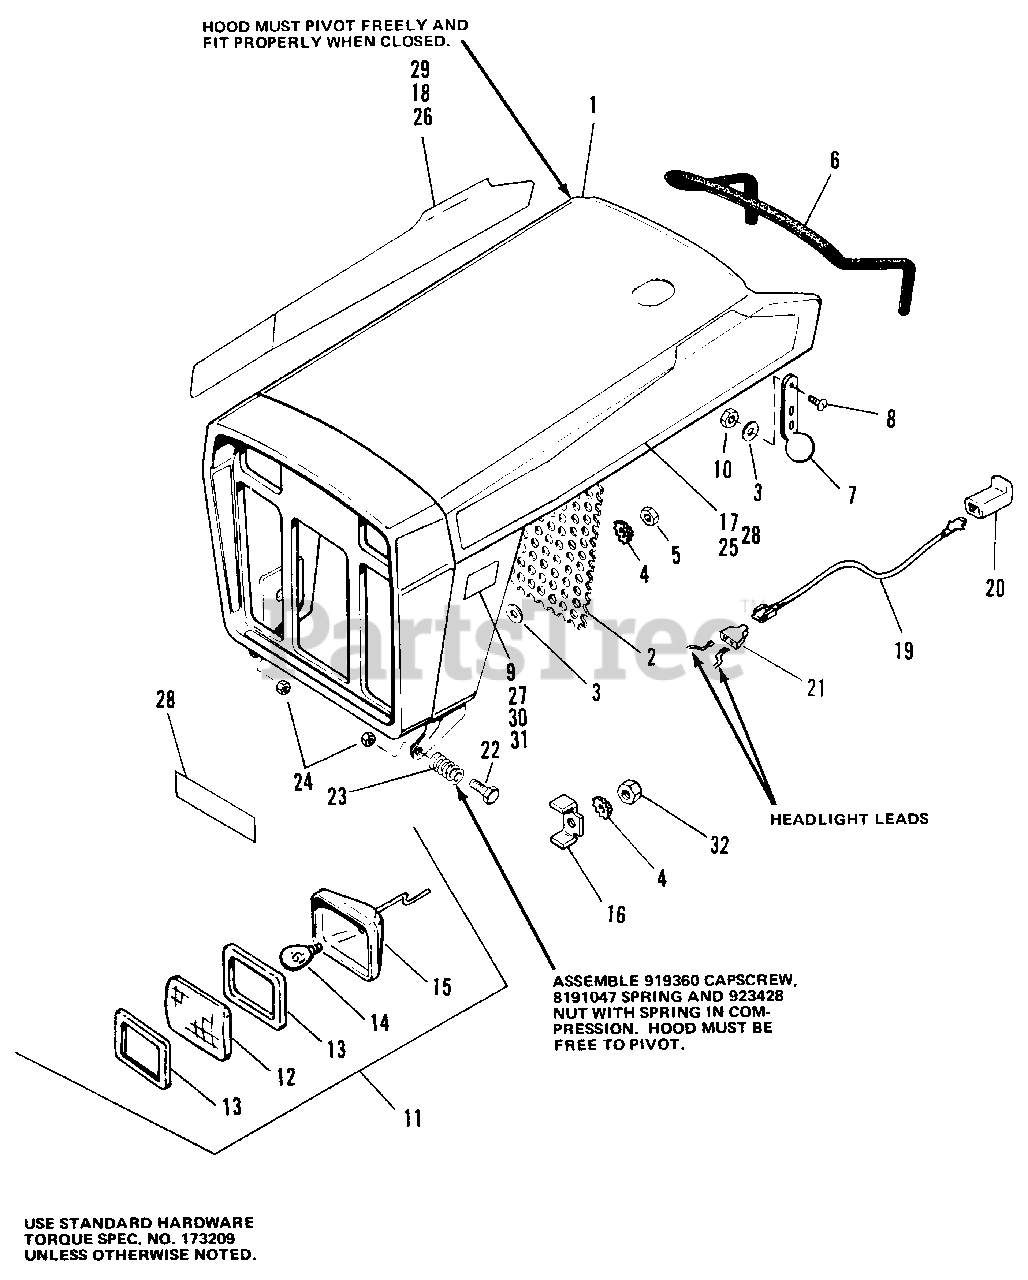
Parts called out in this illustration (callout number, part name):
1	HOOD & GRILLE ASSEMBLY
2	SCREEN, Grille
3	WASHER, Special
4	LOCKWASHER, Ext. Tooth, No. 10
5	NUT, Hex, Mach., No. 10-24
6	MOULDING, Hood
7	STRAP, Hood
8	SCREW, Truss Hd., No. 10-32 x 1/2
9	DECAL, 7016-6 Speed (7016)
10	LOCKNUT, Hex, No. 10-32
11	LIGHT ASSEMBLY
17	DECAL, L.H. Hood, Sovereign (7016)
18	DECAL, R.H. Hood, Sovereign (7016)
19	WIRE ASSEMBLY
20	BODY, Connector
21	CONNECTOR, Insulated
22	CAPSCREW, Hex Hd., 3/8-16 x 1-1/2
24	NUT, Hex, 3/8-16
25	DECAL, L.H. Hood, Landlord (7010)
26	DECAL, R.H. Hood, Landlord (7010)
27	DECAL, 7010 6-Speed (7010)
28	DECAL, Simplicity
